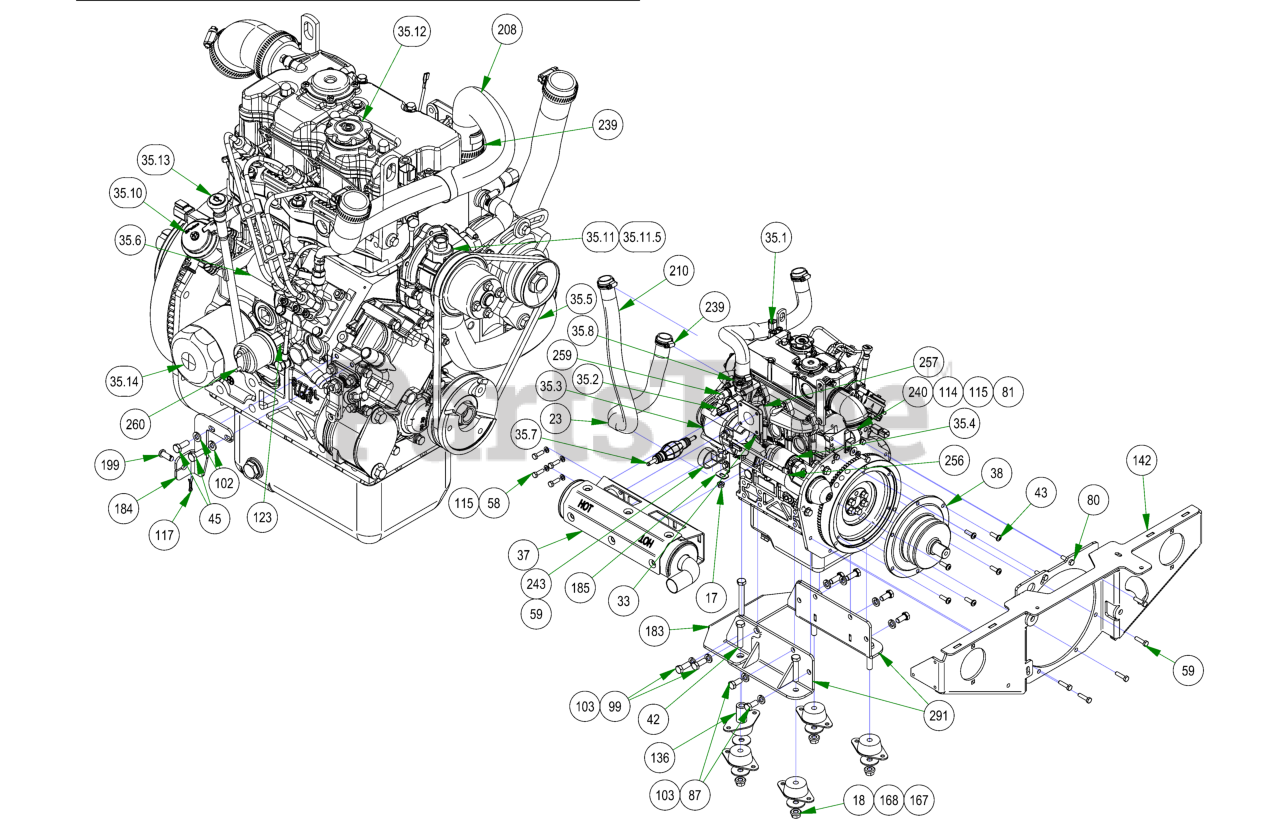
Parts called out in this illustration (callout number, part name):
23	2019 Plastic Mesh Hose Loom
33	Diesel Muffler Gasket
35	24.7HP Perkins Engine, 403J-11
35.1	OIL PRESSURE SWITCH
35.2	COOLANT TEMPERATURE SWITCH
35.3	ALTERNATOR
35.5	ALTERNATOR BELT
35.6	FUEL SHUTOFF SOLENOID
35.7	FUEL PRIMING BULB PUMP
35.8	THERMOSTAT GASKET
35.10	FUEL LIFT PUMP
35.11	WATER PUMP WITH GASKET
35.11.5	THERMOSTAT
35.12	OIL FILLER CAP
35.13	OIL LEVEL DIPSTICK
35.14	OIL FILTER
37	2019 Renegade 1100cc Diesel Muffler
38	2019 Diesel Stub Shaft Double V
42	1/2-13 X 2-1/2 HEX CAP SCREW GR 5 ZINC
43	5/16-18 X 1 BUTTON TORX CAP SCREW ZINC
44	5/16-18 X 2-1/4 HEX CAP SCREW (GR.5) ZINC
58	M8-1.25 X 25MM DIN 933 HEX TAP BOLT (CL 10.9) ZINC
75	1/2-13 X 4 HEX CAP SCREW (GR.8) ZINC YELLOW
80	M8-1.25 X 30MM DIN 933 HEX TAP BOLT (CL 10.9) ZINC
81	M8-1.25 X 20MM DIN 933 HEX TAP BOLT (CL 8.8) ZINC
87	M12-1.25 X 25MM DIN 961 HEX TAP BOLT (CL 8.8) ZINC
99	M12-1.25 X 30MM DIN 961 HEX TAP BOLT (CL 8.8) ZINC
103	1/2 SPLIT LOCKWASHER (GR.8) ZINC/YELLOW
114	5/16 USS FLAT WASHER (7/8 OD) ZINC
115	5/16 SPLIT LOCKWASHER ZINC
117	3/32 X 1/2 COTTER PIN ZINC
123	8mm x 1/8 mpt Adaptor
129	.380 ID X .625 OD X 1.500 LGTH 2019 OUTLAW BRAKE HANDLE SPACER ZINC
132	ACS Spacer 3/4x3/8x1/4
136	1 3/4" Pulley Spacer
168	.520 ID X 1.750 OD X .120 THICK FLAT WASHER ZINC
183	2022 Renegade Diesel Front Engine Mount
184	Throttle Bracket
185	Diesel Radiator Hose Clamp Bracket
199	1/4 X 5/8 CLEVIS PIN PLAIN
208	2019 Diesel Radiator Hose Upper
209	2019 Diesel Air intake Hose
210	2019 Diesel Radiator Hose Lower
239	1 1/8" Hose Clamp
240	Diesel Hydraulic Hose Clamp
256	Red Battery Cable Alternator to Starter Cable
257	2022 DIESEL JUMPER WIRE, WHITE, 14AWG
259	Coolant Temperature Sender
260	Oil Pressure Guage with Sender
284	Patent Decal (ROGUE/RENEGADE)
